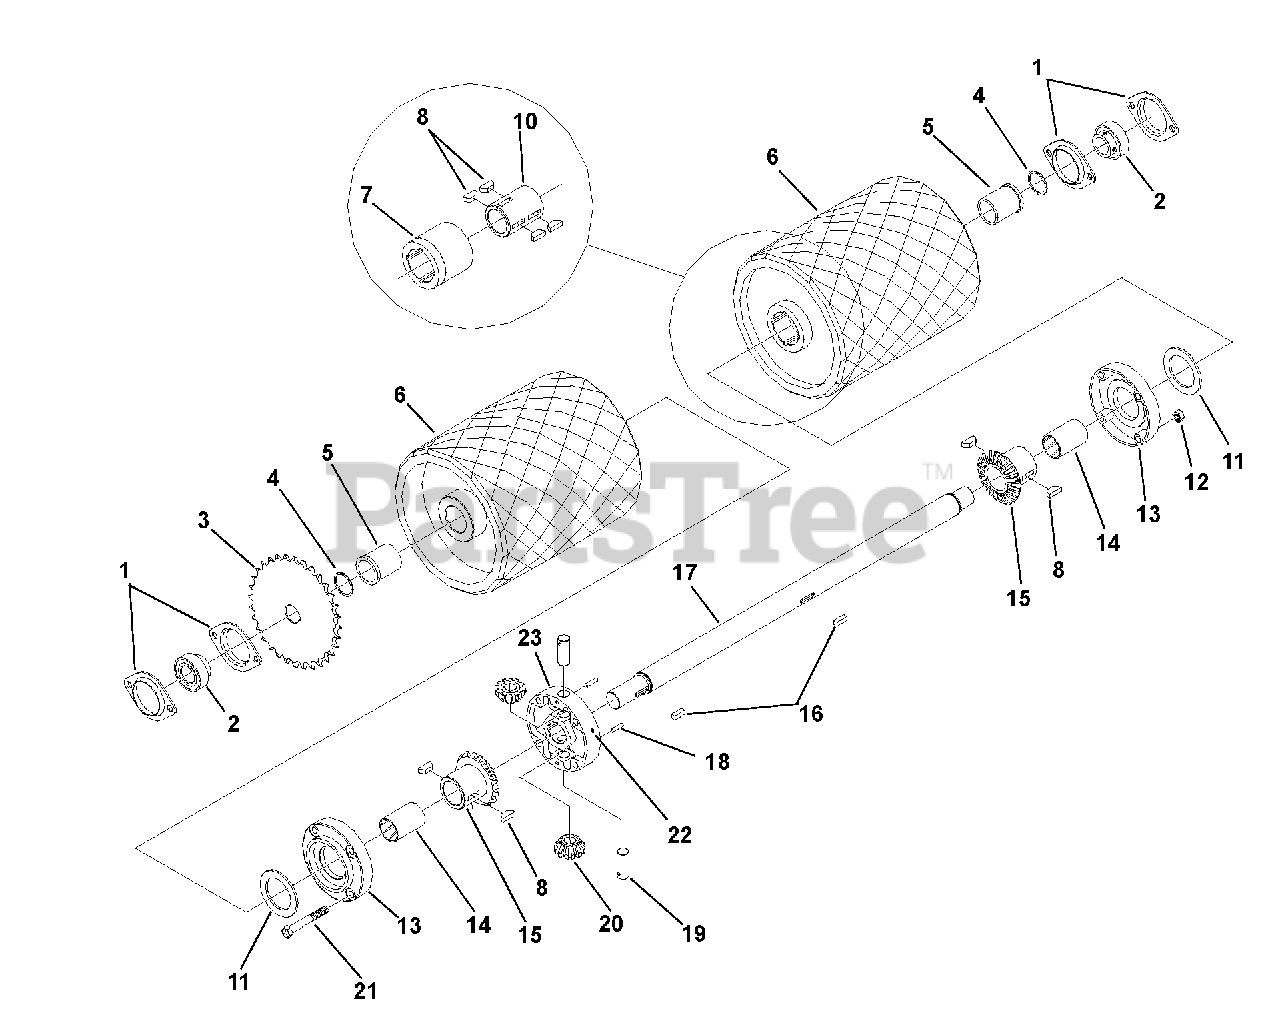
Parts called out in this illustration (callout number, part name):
1	Bearing Flange
3	Sprocket, 40-Tooth
4	Snap Ring, Axle
6	Roller, Traction
7	Roller, Extension (995313)
8	Key, Woodruff .25 x .875 (995310)
9	Key, Woodruff .25 x .875 (995313)
10	Sleeve, Keyed
12	Nut, Hex .38-24
13	Plate, Side
15	Gear, Differential Axle With Bushing
16	Key, Square .25 x .25 x .75
17	Axle, 25-Inch (995310)
18	Pin, Groove .187 x 1
19	Shaft, Differential Pinion
21	Cap Screw, Hex Head .38-24 x 2.75
22	Grease Fitting .25-28
23	Plate, Center
